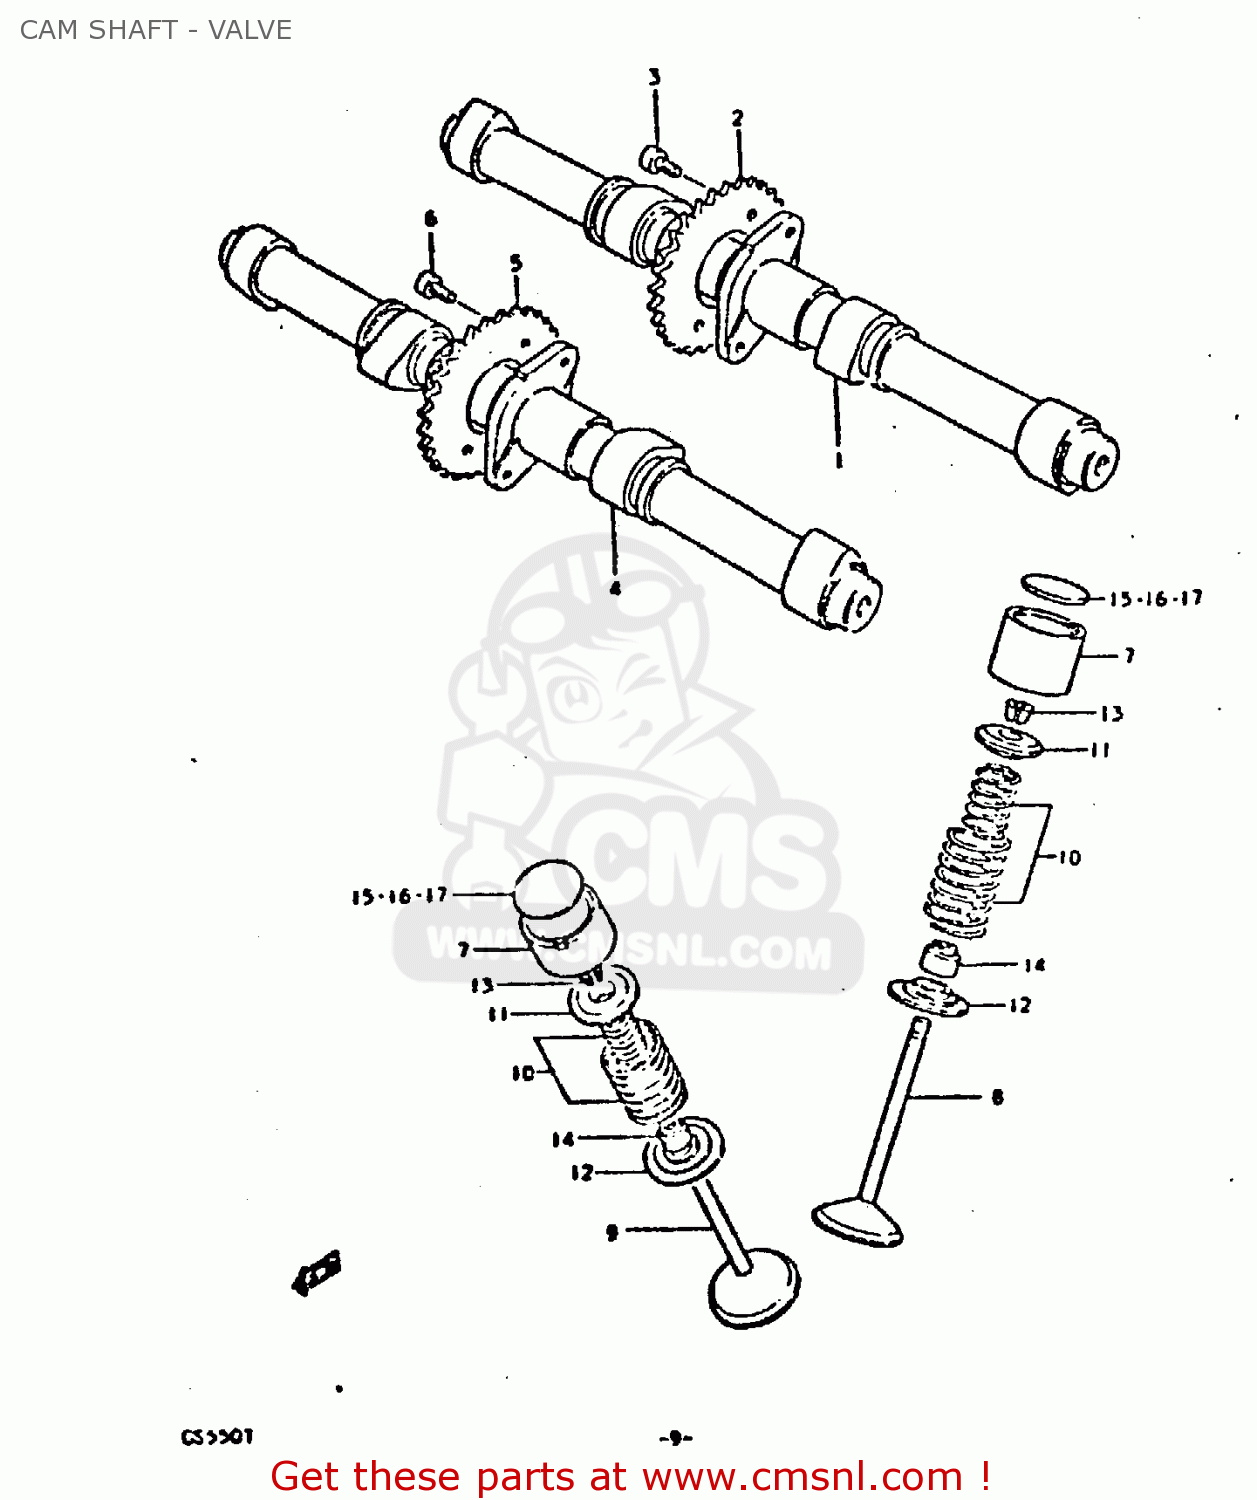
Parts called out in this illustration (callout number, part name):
1	CAMSHAFT
2	SPROCKET,CAMSHAFT
3	BOLT 6X11
4	CAMSHAFT,EXHAUST
5	SPROCKET,EXHAUST CAMSHAFT
6	BOLT 6X11
7	TAPPET
8	VALVE,INTAKE
9	VALVE,EXHAUST
10	SPRING SET,VALVE
11	RETAINER,VALVE SPRING
12	SEAT,VALVE SPRING
13	COTTER VALVE
14	SEAL,OIL(7X14.4X9)
15	SHIM,TAPPET
16	SHIM,TAPPET
17	SHIM,TAPPET
